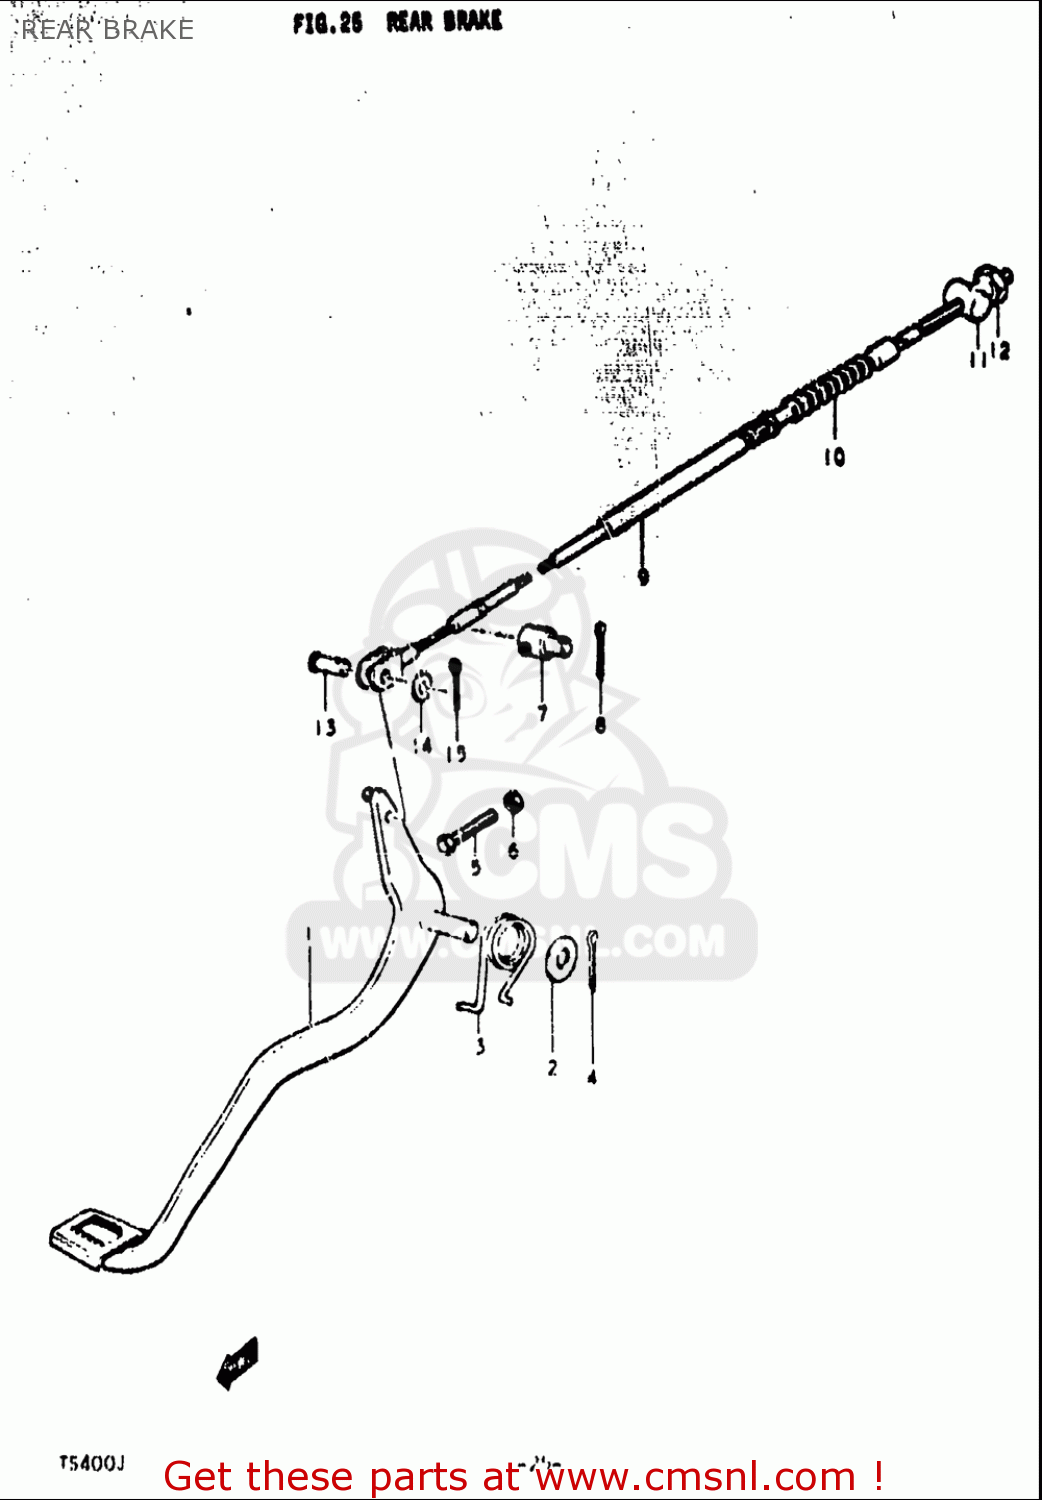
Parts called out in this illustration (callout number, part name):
2	WASHER
3	SPRING
4	PIN
6	NUT
8	PIN
9	CABLE,RR BRAKE
10	SEAL,DUST
11	PIN(13X18)
12	NUT
13	PIN(L:13.5)
14	WASHER
15	PIN
